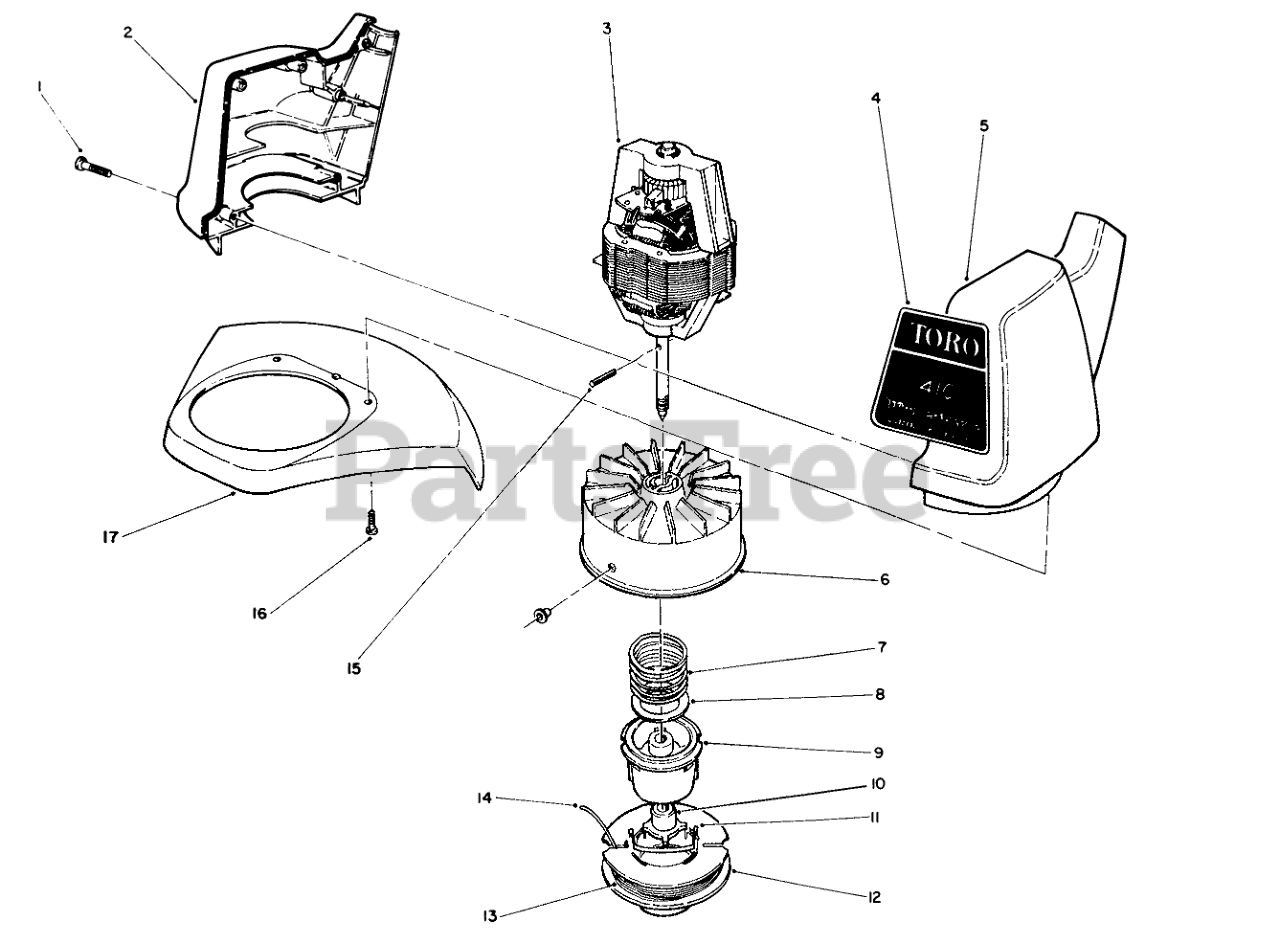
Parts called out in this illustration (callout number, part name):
1	SCREW-PPH
2	RH HOUSING, 1410
3	MOTOR, 1410 TRIMMER
4	DECAL, 1410
5	LH HOUSING, 1410
6	Drum & Eyelet Assembly
7	SPRING COMPRESSION
8	WASHER-FLAT
9	SPOOL CORE
10	DRIVER
11	SADDLE-SPOOL CAP
12	Empty Spool
13	Cutting Line (50 .065" Dia.)
14	LINE-FILIMENT
15	COIL PIN
16	SCREW-PPH
17	Shield Assembly
